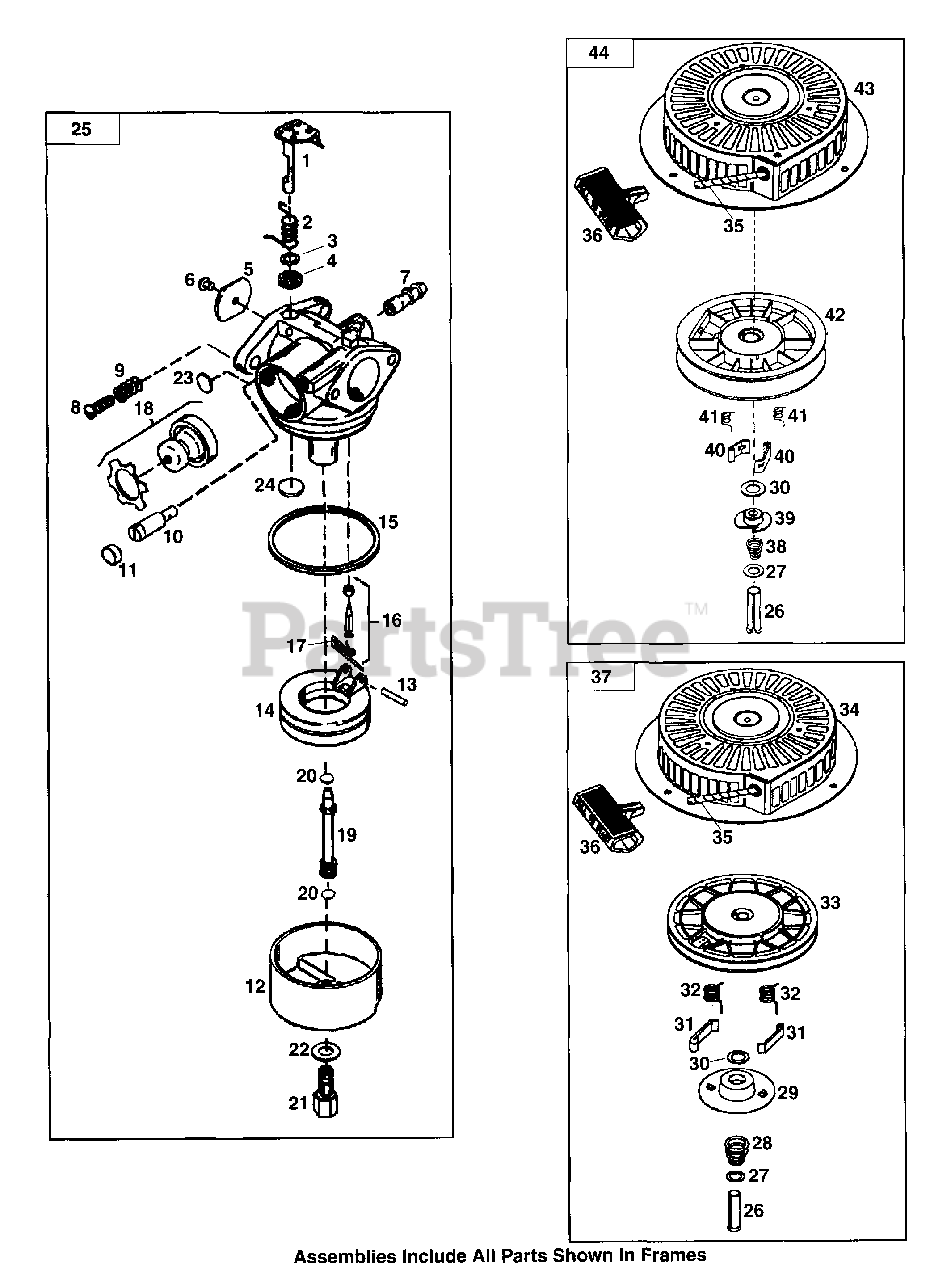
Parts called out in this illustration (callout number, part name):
1	Throttle Shaft & Lever Ass'y
2	Throttle Return Spring
3	Dust Seal Washer
4	Dust Seal (Throttle)
5	Throttle Shutter
6	Shutter Screw
7	Fuel Fitting
8	Throttle Crack/Idle Speed Screw
9	Tension Spring
10	Idle Restrictor Screw
11	Idle Restrictor Screw Cap
12	Float Bowl
13	Float Shaft
14	Float
15	Float Bowl "O" Ring
16	Inlet Needle, Seat & Clip
17	Spring Clip
18	Primer Bulb/Retainer Ring
19	Main Nozzle Tube
20	Main Nozzle Tube "O" Ring
21	High Speed Bowl Nut
22	Bowl Nut Washer
23	Welch Plug, Idle Mixture Well
24	Welch Plug, Atmospheric Vent
25	Carburetor Assembly
26	Spring Pin,
28	Brake Spring
31	Starter Dog
32	Dog Spring
33	Pulley & Rewind Spring Ass'y
34	Starter Housing Ass'y
35	Starter Rope (98")
36	Starter Handle
37	Rewind Starter Ass'y
38	Brake Spring
40	Starter Dog
41	Dog Spring
42	Pulley & Rewind Spring Ass'y
43	Starter Housing Ass'y
44	Rewind Starter Ass'y
